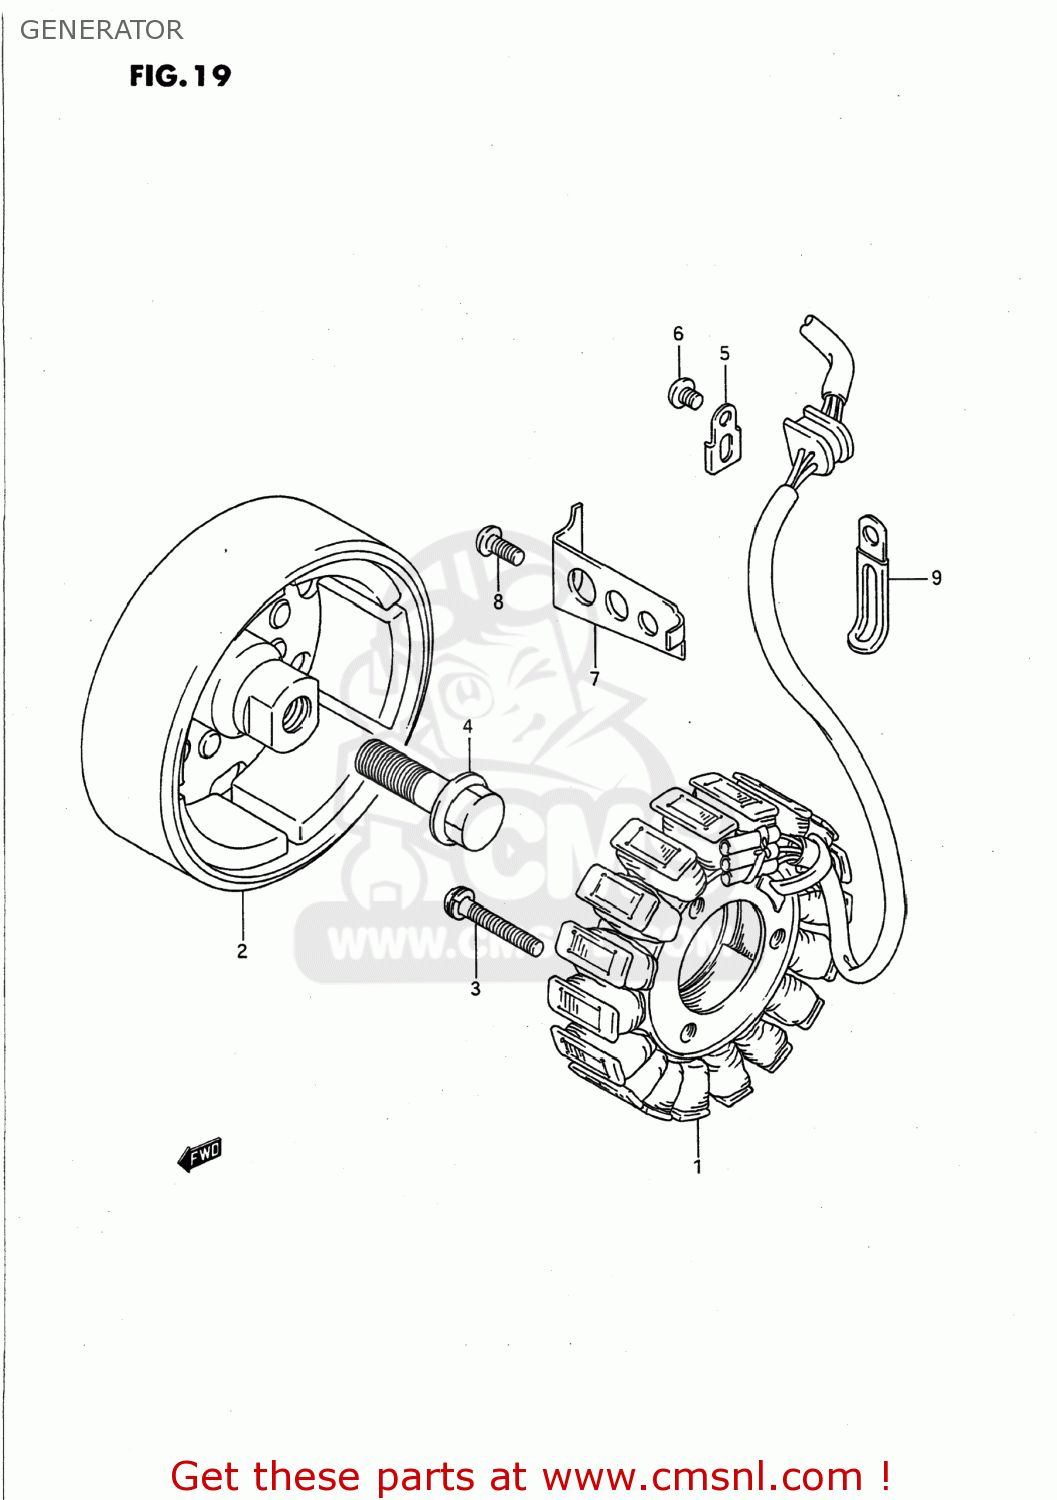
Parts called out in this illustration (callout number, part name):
1	STARTER ASSY
2	ROTOR ASSY
3	SCREW
4	BOLT(12X40)
5	CLAMP,GENERATOR LEAD WIRE
6	SCREW
7	CLAMP,GENERATOR LEAD WIRE
8	SCREW
9	CLAMP
